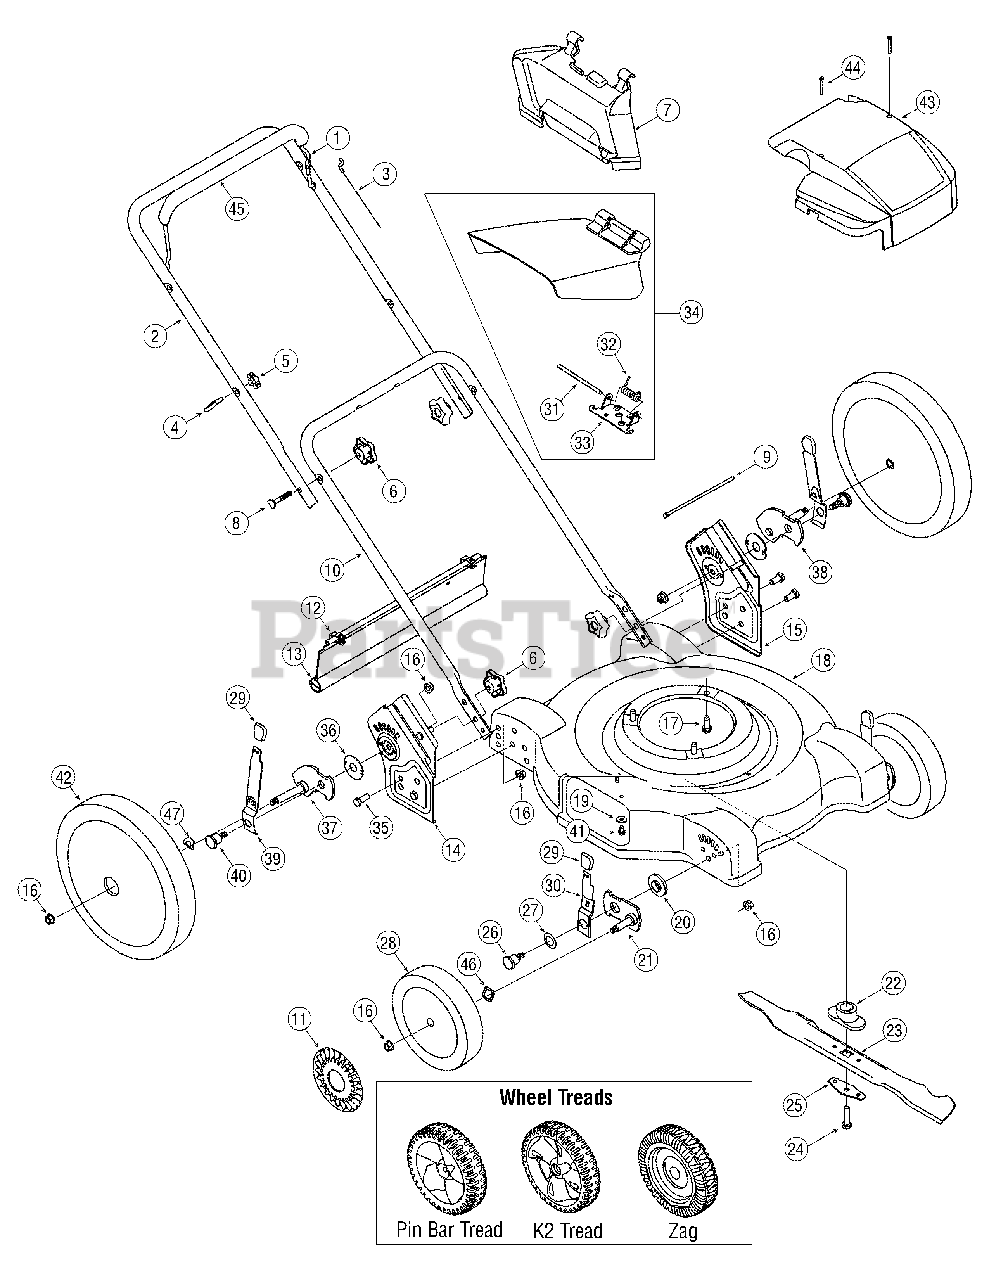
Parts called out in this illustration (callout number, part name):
1	Blade Control
3	Blade Control Cable - 37.25"
3	Blade Control Cable - 40"
3	Blade Control Cable - 48.25"
4	Eye Bolt
5	Wing Nut
6	Star Knob
7	Mulching Baffle
8	Carriage Bolt 5/16-18 x 2.0
9	Cable Tie
11	Hub Cap
12	Hinge Clip
13	Trail Shield
14	Handle Bracket Assembly - RH
15	Handle Bracket Assembly - LH
16	Lock Nut 3/8 -16
17	Hex Washer Screw 3/8-16 x 1.0
19	Bell Washer.265 x.75
20	Height Adjuster Bearing
21	Pivot Arm Assembly
22	Blade Adapter
23	22" Mulching Blade
23	22" Standard Blade
24	Hex Cap Screw 3/8-24 x 1.5
25	Blade Bell Support
26	Shoulder Screw 3/8 - 16 x.302
27	Bell Washer.760 ID x 1.25 OD
28	Front Wheel, 7 x 1.8, Pin Bar
28	Front Wheel, 7 x 2.125, Zag
29	Height Adjuster Knob
30	Front Spring Lever
31	Hinge Pin
32	Torsion Spring
33	Deflector Chute Adapter
34	Side Discharge Chute Assembly
35	Hex Cap Screw 3/8-16 x .75
36	Thrust Brg., .688 ID x 1.94 OD
37	Rear Pivot Arm Assembly - RH
38	Rear Pivot Arm Assembly - LH
39	Rear Spring Lever
40	Shoulder Screw 3/8 - 16 x.442
41	Screw 1/4-20 x.50
42	Rear Wheel, 12 x 1.8, K2 Bar
42	Rear Wheel, 12 x 1.8, Pin Bar
42	Rear Wheel, 12 x 2.125, Zag
43	Engine Shroud
44	Screw, #8-18 x 1.25
45	Bail Cover
46	Wave Washer
47	Spring Washer
